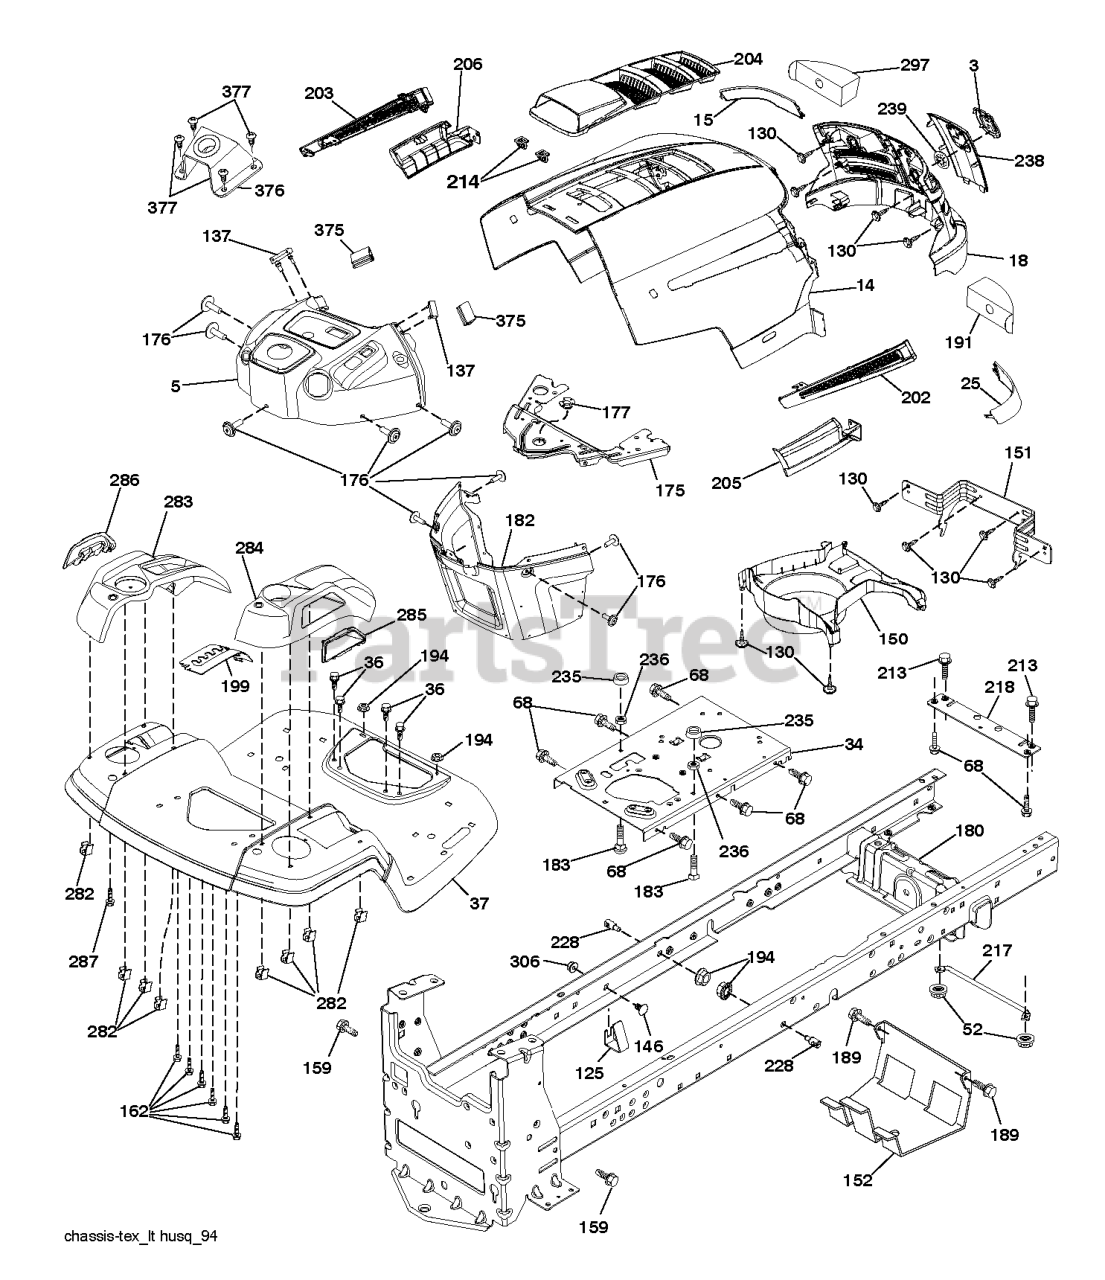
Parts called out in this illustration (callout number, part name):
3	LOGO.HUSQ.GT.LT.CROWN.H
5	Husqvarna TBD
14	HOOD.HUSQVARNA.LT.ORANGE
15	LENS.HUSQVARNA LT.RH
18	GRILLE.SVC.HUSQVARNA.GREY
25	LENS.HUSQVARNA LT.RH
34	PLATE.ENGINE.WELDED.CHASSIS
36	SCREW 5/16"
37	FENDER.TLT.FS.W/CUPHLD.ORANGE
52	LOCKNUT
68	SCR 5/16-18 X 1/2 SELFTAP ZN
125	CLIP.FUEL.LINE
130	SCREW.#10 X 0.750.BOS
137	BUMPER DASH
146	BOLT.RDHD.SHT.SQNK.3/8-16X5/8
151	BRACKET PIVOT
152	SHIELD.BROWNING.W/TEX
159	SCREW, 3/8-16X3/4
162	SCREW.HI-LO.CONSOLE
175	CROSSMEMBER
176	SCREW.#10-24X5/8.RN.QU
177	BUSHING STEERING
180	CHASSIS
182	DASH.LOWER.PREDATOR LT
183	BOLT.5/16-18X1-1/4 FULL THD
189	SCREW
191	INSERT.REFLECTIVE.RH.
194	NUT LOCK HEX FLANGE 5/16-18
199	PLATE.DECK.LIFT.HUSQ.LT
202	VENT.SIDE.HUSQVARNA.LT.RT
203	VENT.SIDE.HUSQVARNA.LT.LFT
204	SUBASM.TOP.VENT.HUSQ.LT
205	SKIRT.SIDE.HUSQVARNA.LT.RT
206	SKIRT.SIDE.HUSQVARNA.LT.LEFT
213	HCS 5/16C X 3/4
214	CLIP.RETAINER.TINNER.
217	ROD.PIVOT.HOOD
218	X-PIECE.HOOD.STOP.NON/
228	STUD.FASTNER.W/ANTI-ROTATE
235	SPACER FENDER
236	NUT.CENTERLOCK.5/16-
238	TRIM.HUSQ LT.668
282	CLIP.RETAINER.CONSOLE.LT.HUSQ
283	CONSOLE.ASM.LFT.RSF.HUSQ.LT
284	CONCOLE.CNTRL.PDL.HUSQ.LT.498
285	CONSOLE INSERT RH
286	CONSOLE.INSRT.LH.HUSQ.LT.BLACK
287	SCREW 1/4X20
297	INSERT REFLECTIVE
306	NUT LOCK FLG 3/8-16 UNC
375	BUMPER CLIP-ON. DASH 1"
376	MOUNT.ASM.HUSLT.UPPER.STRNG
377	SCREW 10 X 1/2 ZN PL PHIL PAN
